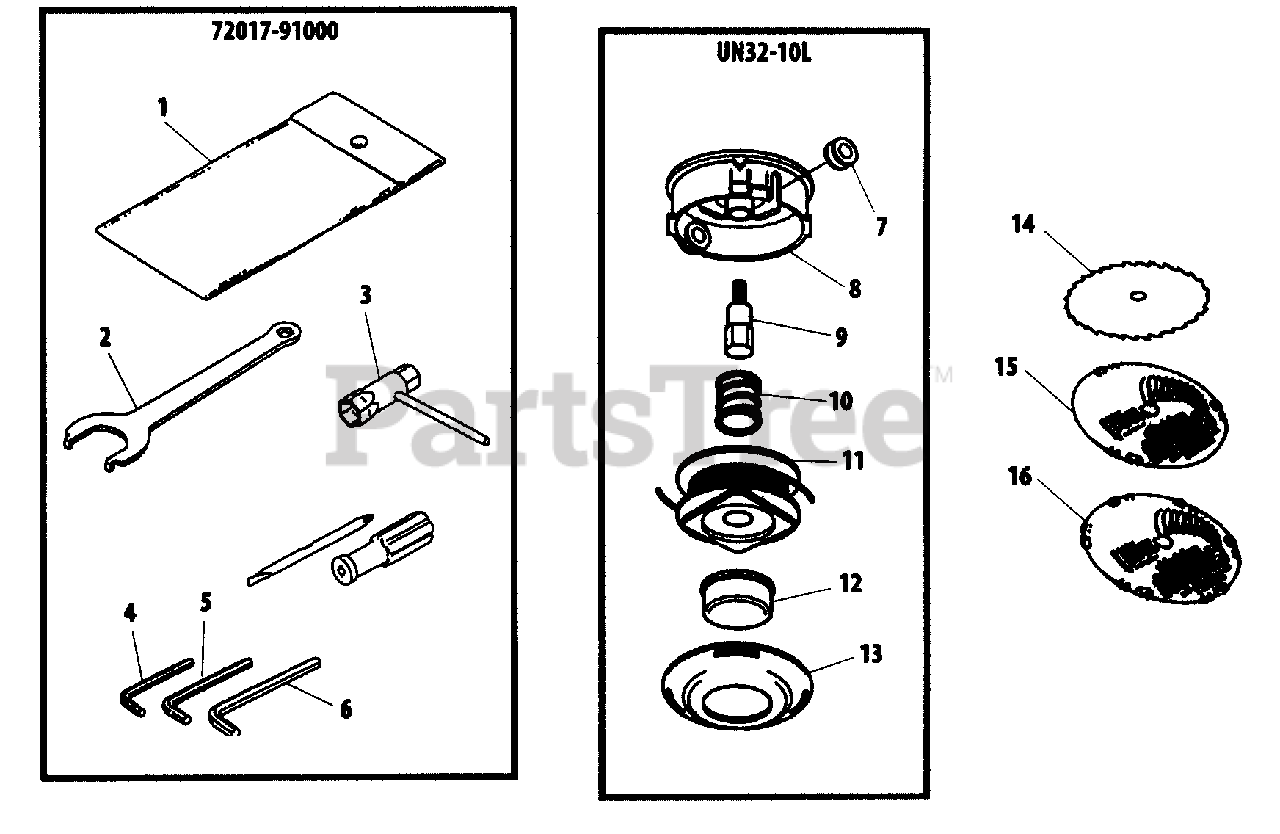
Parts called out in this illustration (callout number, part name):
1	BAG, TOOL
2	SPANNER
3	WRENCH, SPARK PLUG -- 17×9 MM
4	WRENCH, ALLEN 4 MM
5	WRENCH, ALLEN 5 MM
6	WRENCH, ALLEN 3 MM
9	SHAFT BOLT 10 MM LH
14	BLADE - 30 TOOTH -- 9"
15	BLADE - 6 TOOTH -- 9" TORNADO
16	BLADE - 12 TOOTH -- 9" TORNADO
72017-91000	TOOL KIT, SERVICE
UN32-10L	TRIMMER HEAD ASSY
